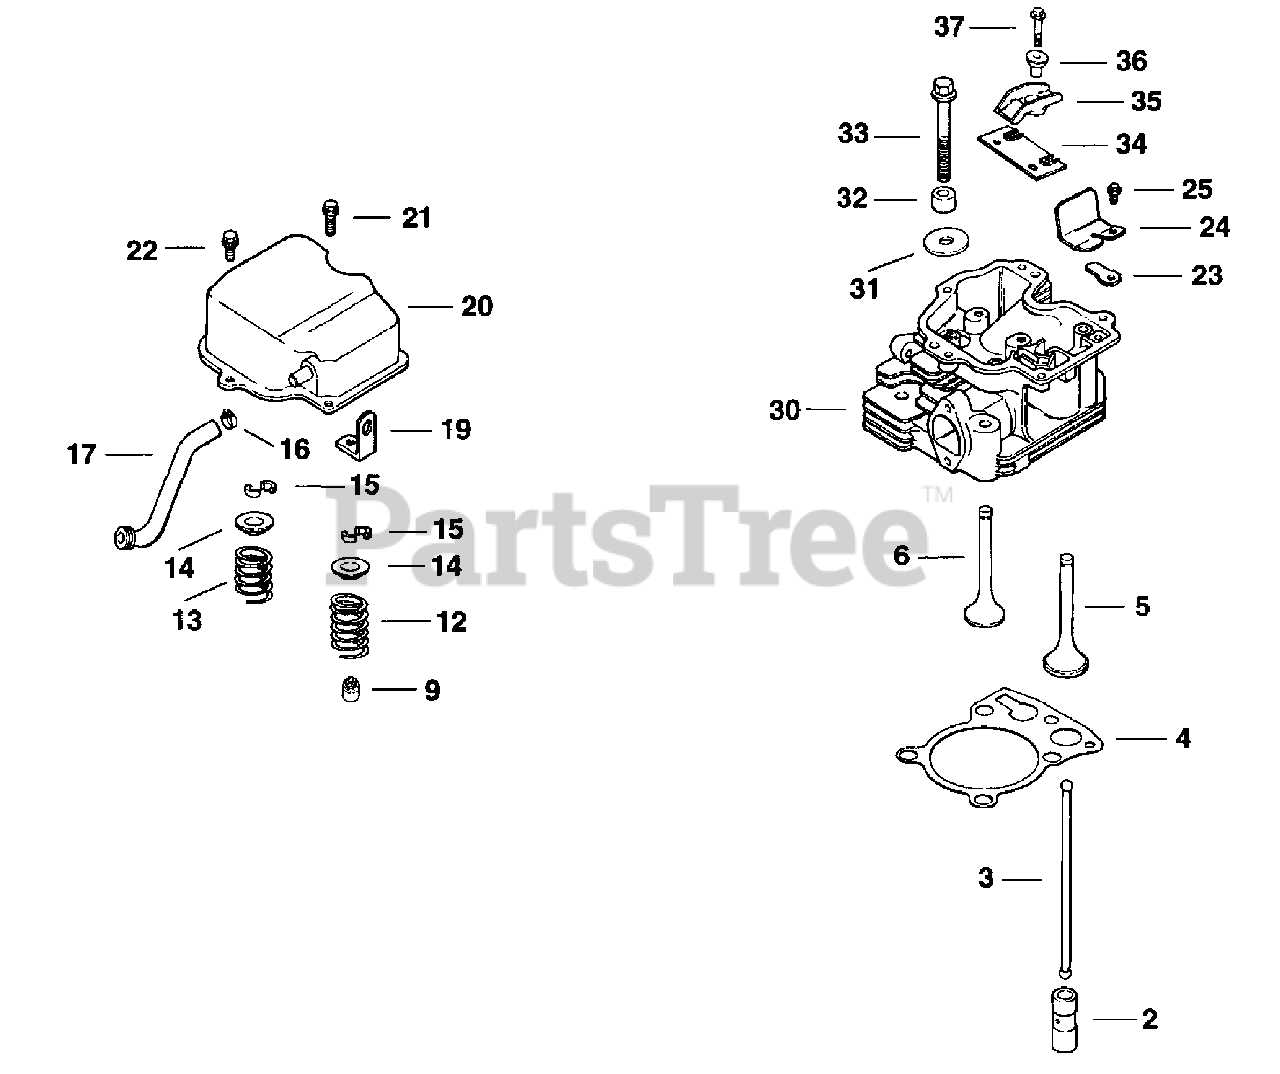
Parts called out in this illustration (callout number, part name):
2	LIFTER - USE 12 351 02
4	GASKET, CYLINDER HEAD
5	VALVE, INTAKE
5	VALVE, INTAKE (.25 MM)
6	VALVE, EXHAUST
6	VALVE, EXHAUST (.25 MM)
9	SEAL - USE 24 032 05
13	SPRING
14	RETAINER, VALVE SPRING - USE 25 173 28-S
15	KIT, RETAINER
16	CLAMP, HOSE 1/2" USE 25 237 14-S
17	HOSE, BREATHER - USE 12 326 25-S
20	COVER - USE 12 096 07
21	SCREW - USE M-645025
22	SCREW - USE M-645020
23	REED, BREATHER
24	RETAINER, REED
25	SCREW - USE M-545010
31	WASHER, FLAT 13/32"
32	SPACER, HEAD BOLT EXHAUST PORT
